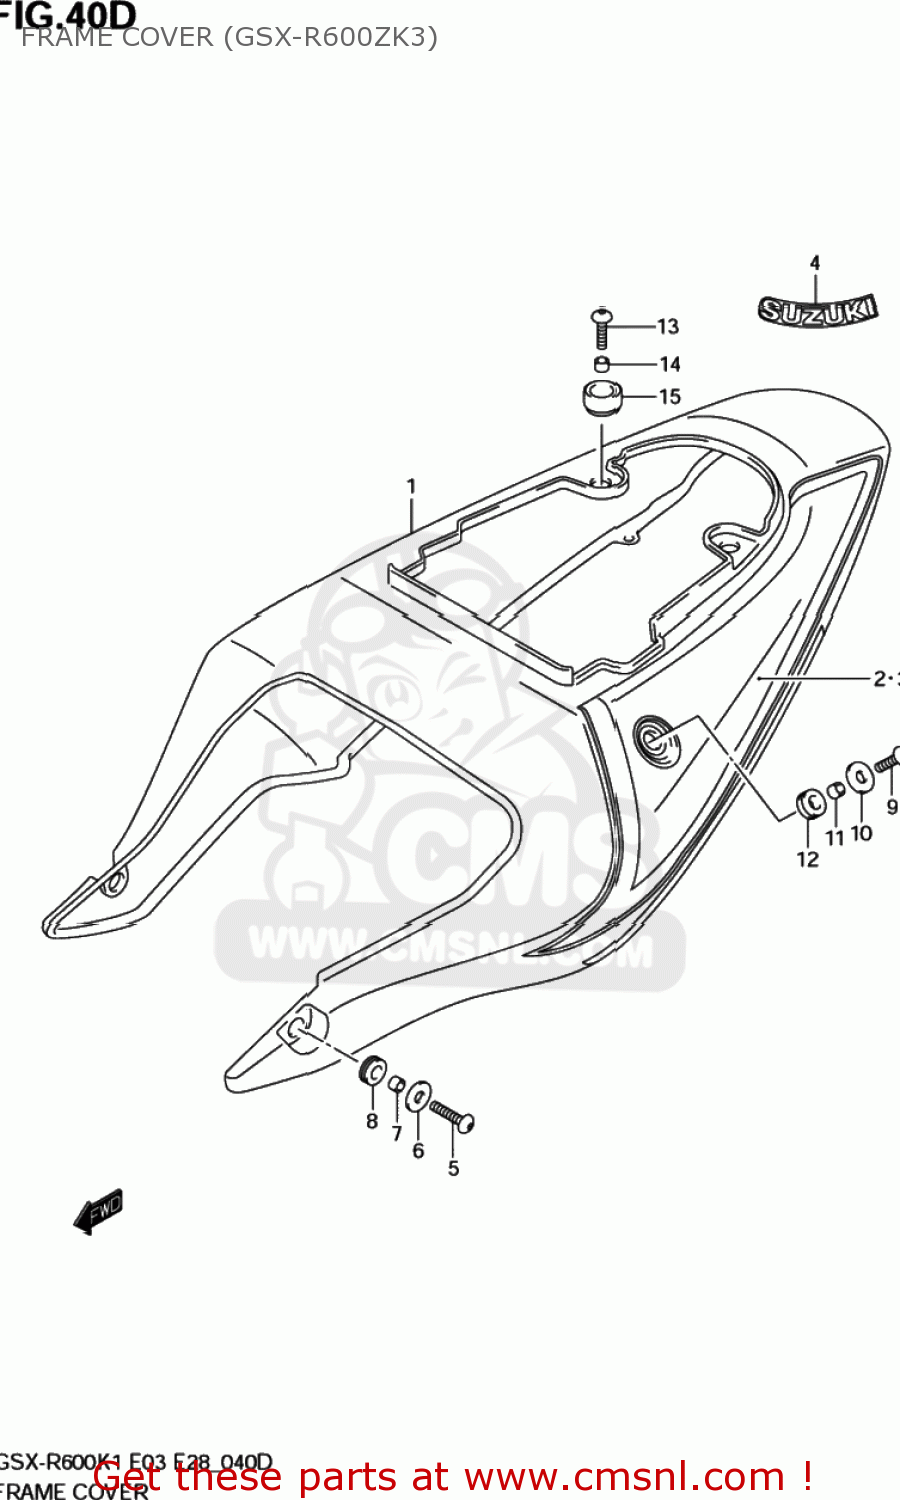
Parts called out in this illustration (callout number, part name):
1	COVER ASSY,FRAME
2	TAPE,FRAME COVER,R
3	TAPE,FRAME COVER,L
4	EMBLEM,SUZUKI
5	SCREW(6X30)
6	WASHER(6.5X20X2)
7	SPACER(6.5X10X7)
8	CUSHION,FRAME COVER FR
9	SCREW(6X25)
10	WASHER(6.5X20X2)
11	SPACER(6.5X10X7)
12	CUSHION,FRAME COVER SIDE
13	SCREW(6X25)
14	SPACER(6.5X10X9.4)
15	CUSHION
